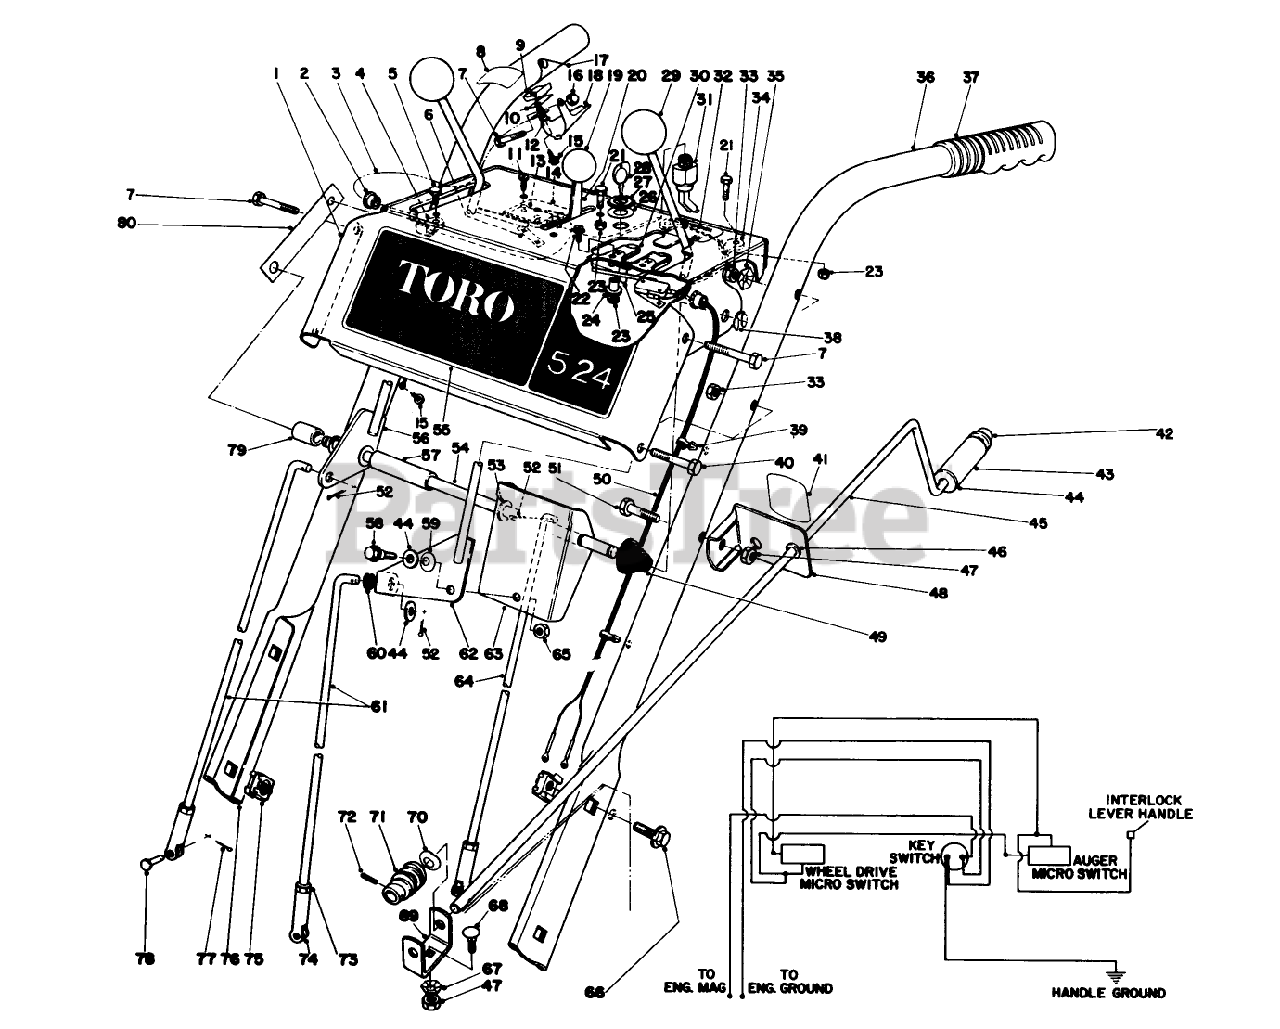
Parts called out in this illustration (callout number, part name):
5	SCREW-HWHTF
6	NUT-SPEED
7	SCREW-HH
10	INTERLOCK CONTACT
11	SCREW-SPH
12	BUSHING-INSULATOR
13	MICRO SWITCH
16	NUT-CAP
22	Screw
24	Spacer Interlock
25	INTERLOCK SPRING
26	WASHER-LOCK
31	SWITCH-ON / OFF
38	Klip Ring
39	Wire Mount
40	SCREW-HH
42	NUT-PUSH
44	WASHER-FLAT
47	NUT-LOCK, NI
49	CONICAL SPRING
51	SCREW-HH
52	PIN-COTTER
53	WASHER-FLAT
54	PIVOT ROD
56	LEVER WA
57	SHIFT LEVER SPACER
60	GROMMET-RUBBER
65	NUT-LOCK, CONE
66	SCREW-HHF
67	WASHER-LOCK
68	BOLT-CARR
70	WASHER-SPRING
71	GEAR-WORM, CHUTE
72	PIN-SPRING
73	SCREW-CARR
77	PIN-COTTER
78	PIN-CLEVIS
79	AUGER LEVER SPACER
